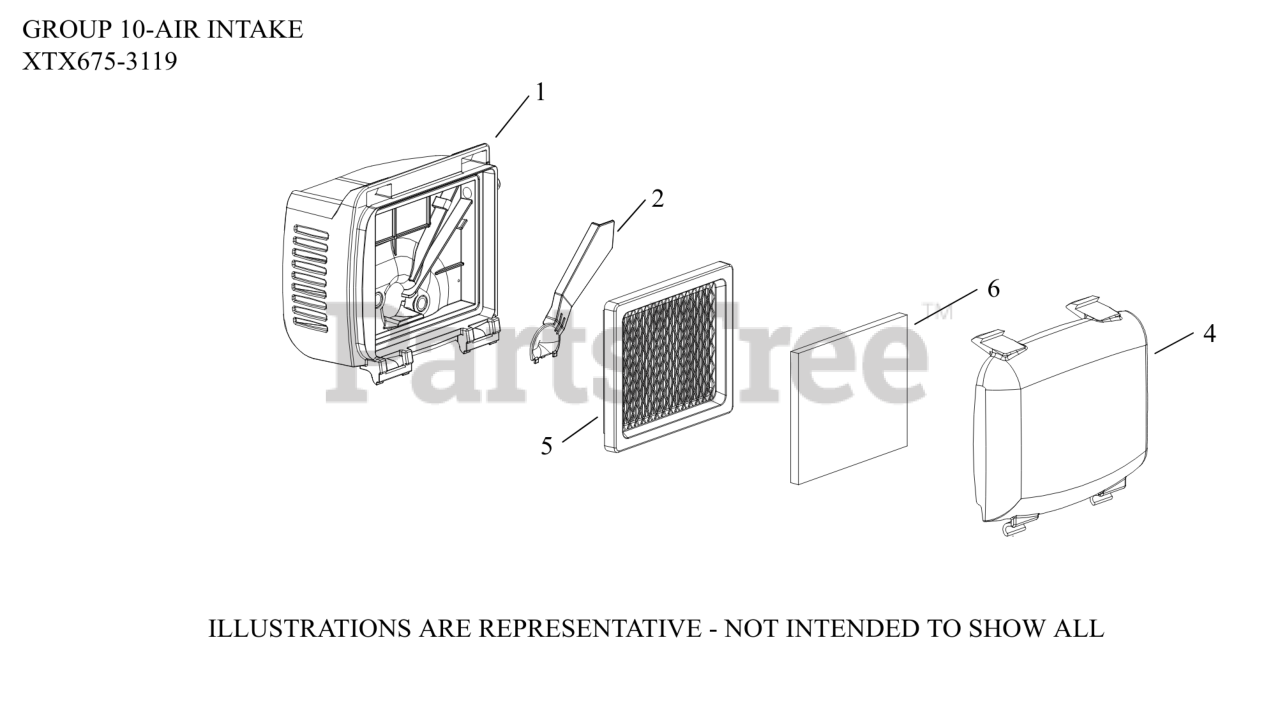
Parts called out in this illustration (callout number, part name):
1	BASE, AIR CLEANER
4	COVER, AIR CLEANER
5	ELEMENT, AIR FILTER
6	ELEMENT, PRE-FILTER FOAM
